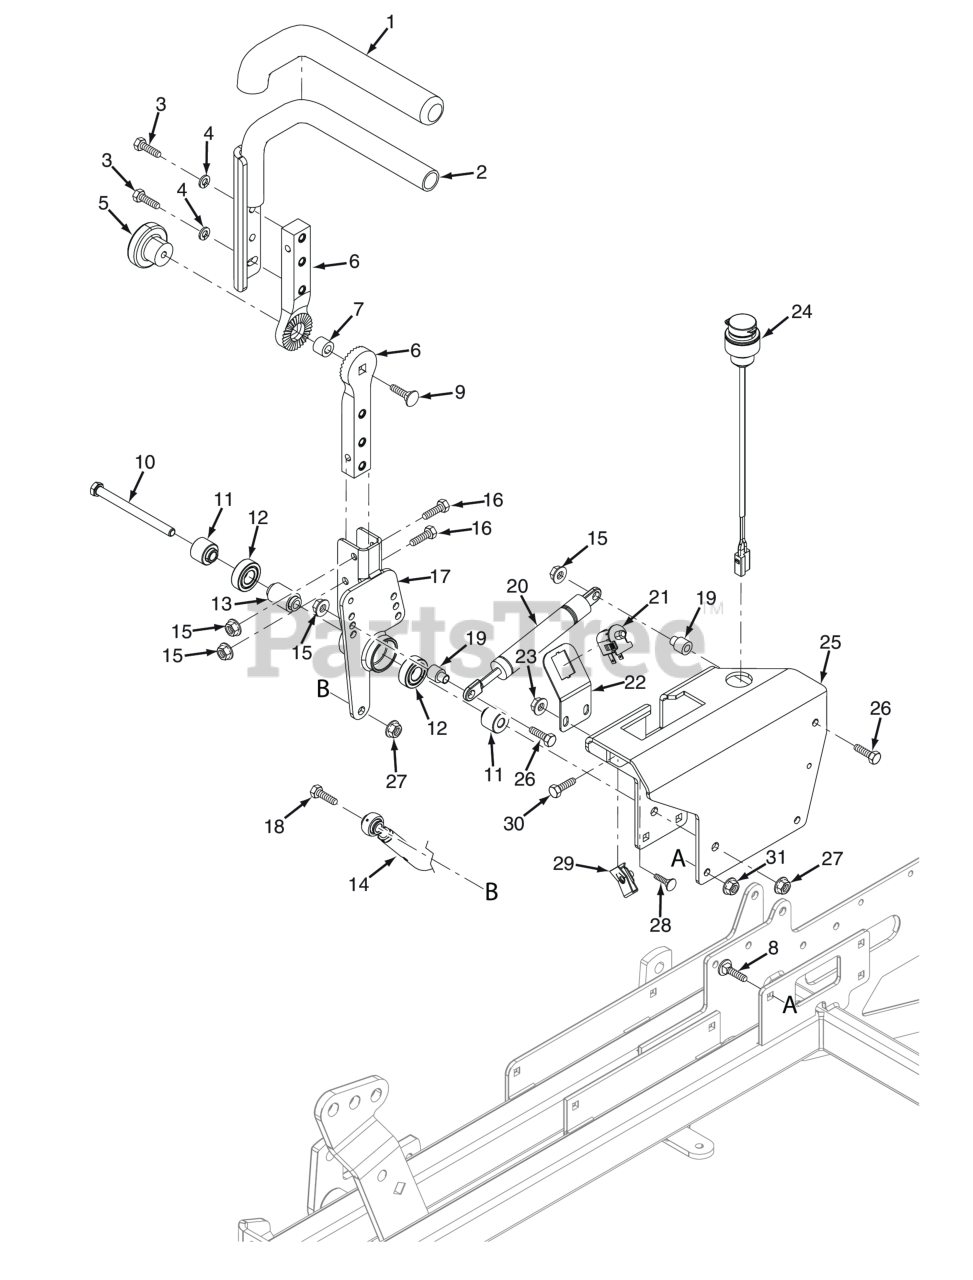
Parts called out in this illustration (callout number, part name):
1	Grip, Control Handle
2	Handle Bar w/Grip - RH
3	Bolt, Heax Head 5/16-18 x 1" (48V / 52V)
4	Lockwasher, 5/16 (.317 x .586 x .078) Helical Spring
5	Knob, Control Handle
6	Pivot, Control Lever
7	Spacer, Rubber
8	Bolt, 5/16-18 x .75 RHSN Carriage
9	Bolt, RDHD Carr. 3/8-16 x 1-1/2 (52" & 61")
10	Bolt, 3/8 - 16 x 4 - 1/2" Hex Head
11	Spacer, Controls
12	BEARINGS, BALL, NEUTRAL RETURN
13	Spacer, Bearing
14	Steering Link Assembly, SCZII
15	HEX NUT, ELASTIC STOP LOCK, 5/16-18
16	Bolt, Hex Head 5/16-18 x 1-1/2" - Front
17	Pivot Weldment, Control Arm RH
18	Bolt, Hex Head 3/8-16 x 1-1/2" B&S 32BV
19	Spacer, Pump Dampener
20	Damper, Steering
21	Switch, Interlock, Normally Open
22	Bracket, Operator Presence Switch
23	Nut, Flanged Elastic Stop 1/4-20
24	Power Plug, 12V
25	Control Plate w/ Decals RH
26	Bolt, Hex Head 5/16-18 x 1-1/2" (Right Front Engine Mounting, Briggs and Kohler Only)
27	HEX NUT, ELASTIC STOP LOCK, 3/8-16
28	Serr. Fl. Hex Head CPSCR, 1/4-20 x 3/4"
29	U-Nut, 3/8-16 (short)
30	Bolt, Hex Head 3/8-16 x 1-1/4" with Thread Lock Patch
31	Nut, Serrated Flange 5/16-18 (Right Front Engine Mounting, Briggs and Kohler Only)
